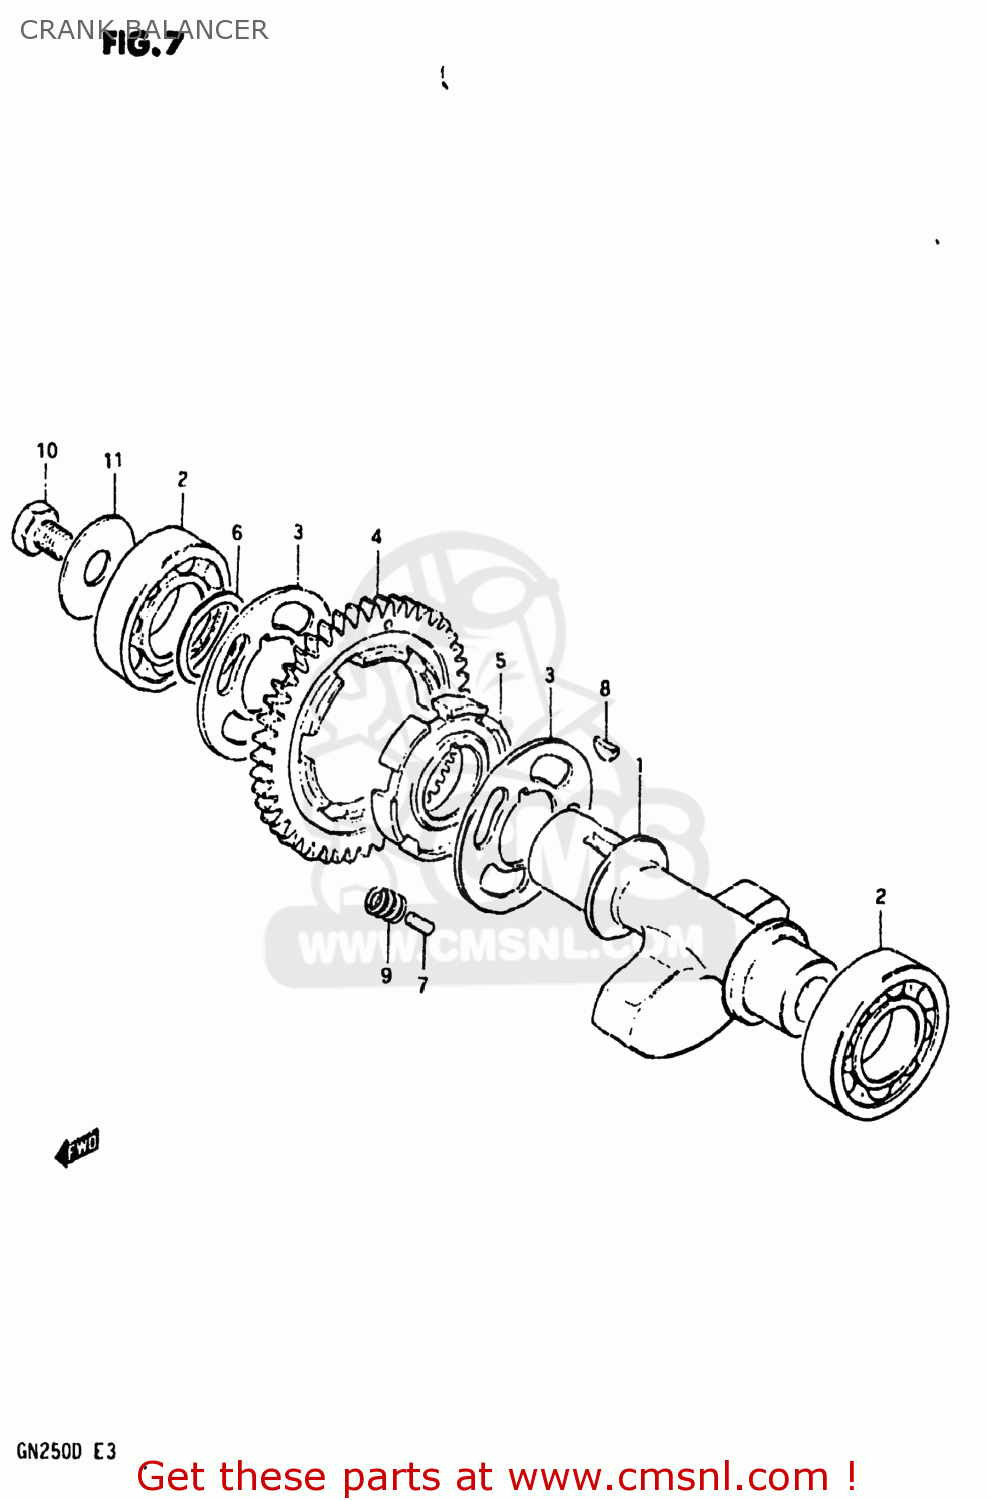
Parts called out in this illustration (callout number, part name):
1	BALANCER,CRANKSHAFT
2	BEARING
3	WASHER
4	GEAR,CRANK BAL DRIVEN(NT:46)
5	RACE,CRK BAL DRIVEN GR INNER
6	SHIM
7	PIN
8	KEY 4MM
9	SPRING
10	BOLT ,12X16
11	WASHER
